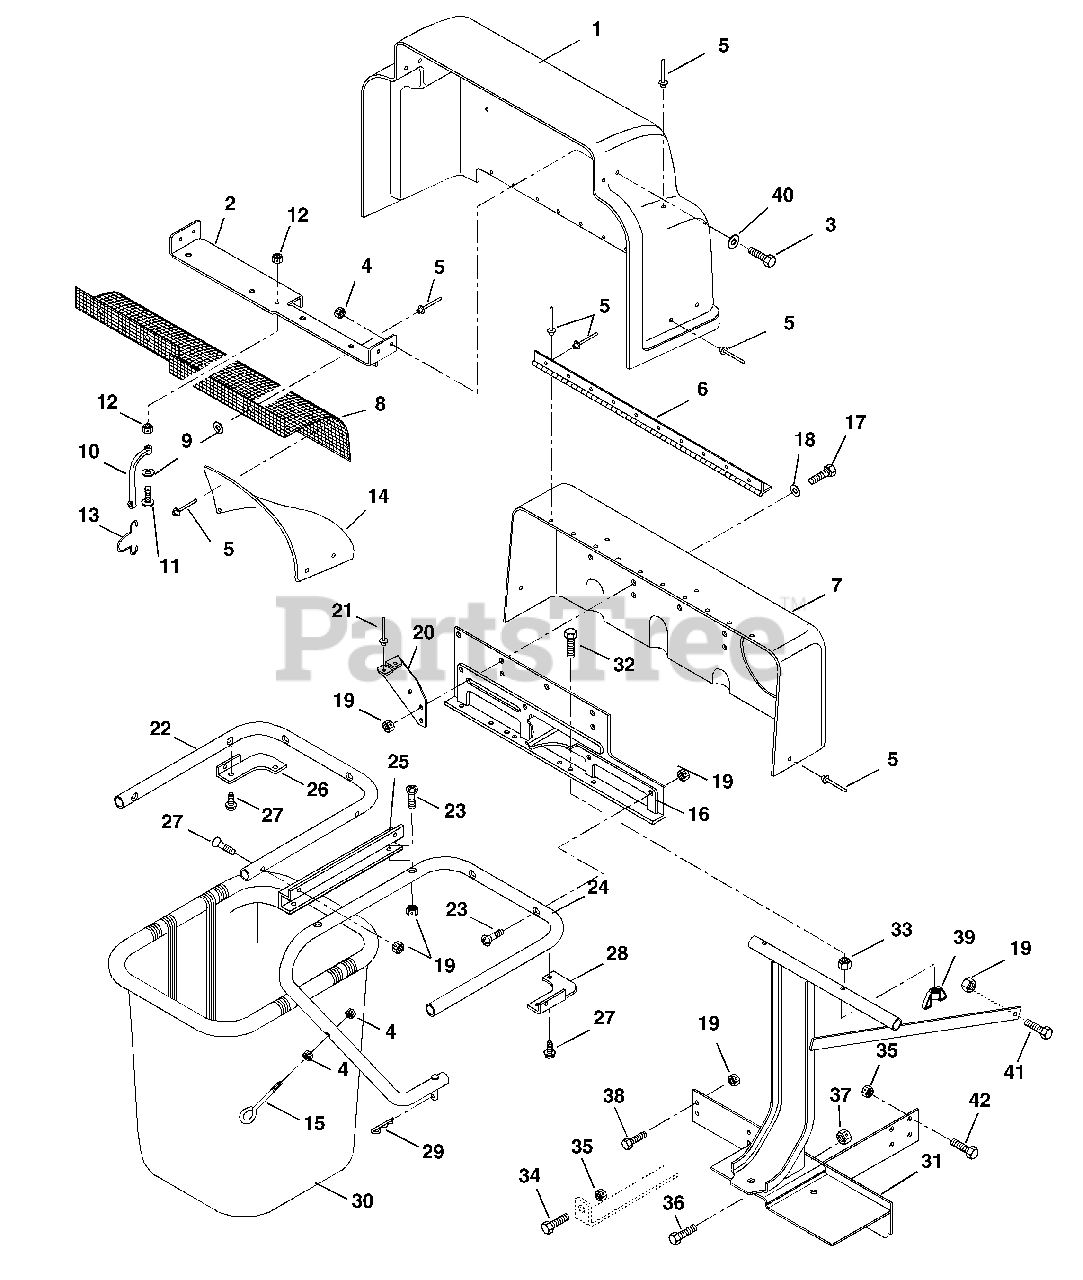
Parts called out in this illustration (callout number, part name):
1	Hinged Cover w/Decals
2	Cover Bracket
3	Bolt-Hex .25-20 x .50 Grade 2
4	Nut-Locking-Center .250-20
5	Rivet-Pop .187 x .402
7	Stationary Cover
9	Washer-Flat-Steel .219 x .50 x .049
10	Battery Strap
11	Screw-Machine 10-24 x .88
12	Nut-Locking Top 10-24
16	Mounting Bracket
17	Bolt-Hex .31-18 x .88 Grade 2
18	Washer-Flat-Steel .328 x .875 x .062
19	Nut-Locking .312-18
21	Rivet-Pop .187 x .527
22	Center Tube
23	Screw-Machine .31-18 x 1.50
24	Right Tube
25	Tube Bracket
26	Left Hand Corner Bracket
27	Screw-Tapping .31-18 x .50
28	Right Hand Corner Bracket
29	Pin-Hair Internal .08 x .38 x 1.42
30	Grass Bagger Basket
31	Bagger Frame
32	Bolt-Hex .31-18 x 1.50 Grade 2
33	Nut-Hex .31-18 Grade 2
34	Bolt-Hex .38-16 x 1.25 Grade 5
35	Nut-Locking-Center .38-16 Grade 2
36	Bolt-Hex .50-13 x 1.00 Grade 5
37	Nut-Locking-Center .50-13
38	Bolt-Hex .31-18 x 1.00 Grade 5
39	Nut-Wing .312-18
40	Washer-flat-Steel .281 x .62 x .065
41	Bolt-Hex .31-18 x 1.25 Grade 5
42	Bolt-Hex .38-16 x 1.00 Grade 5
